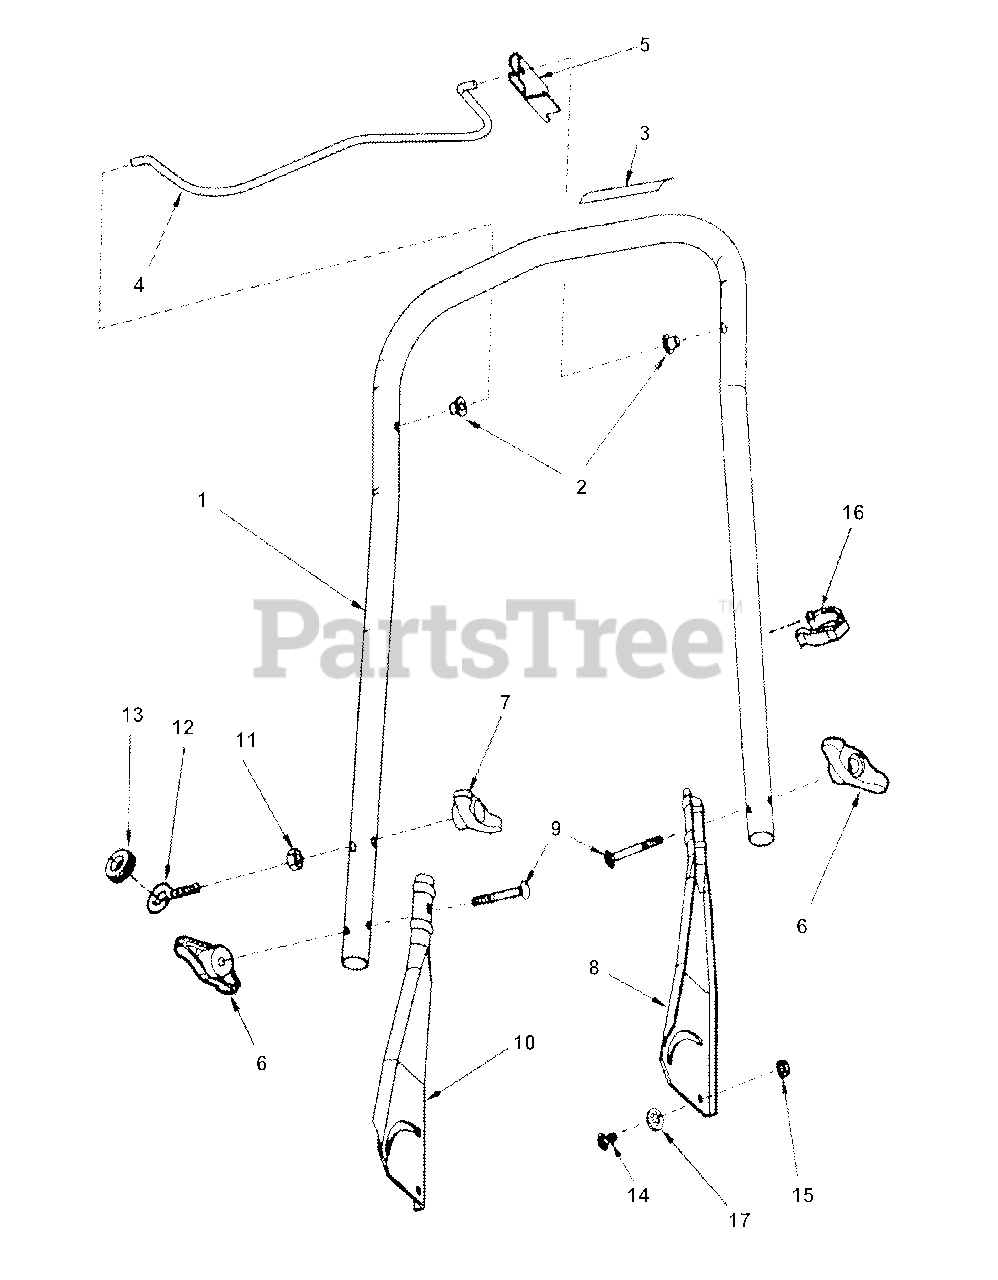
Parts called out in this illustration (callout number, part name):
1	HANDLE, Upper
2	BUSHING, Auger Control
3	DECAL, Auger Control Instruction
4	CONTROL, Auger
5	CLIP, Auger Control
6	KNOB, 1/4-20 Wing (Black)
7	KNOB, 5/16-18 Wing
8	BRACKET, Lower Handle (Left Side)
9	BOLT, 1/4-20 x 2" Square Neck Carriage, Grade 5
10	BRACKET, Lower Handle (Right Side)
11	NUT, 5/16-18 Hex Flange Lock, Grade 5
12	EYE-BOLT, 5/16-18
13	GROMMET, Chute Crank
14	BOLT, 1/4-20 x 1/2" Short Neck Carriage, Grade 5
15	NUT, 1/4-20 Hex Flange Lock
16	CLIP, Wiring Harness
17	RETAINER, 1/4" Bolt
